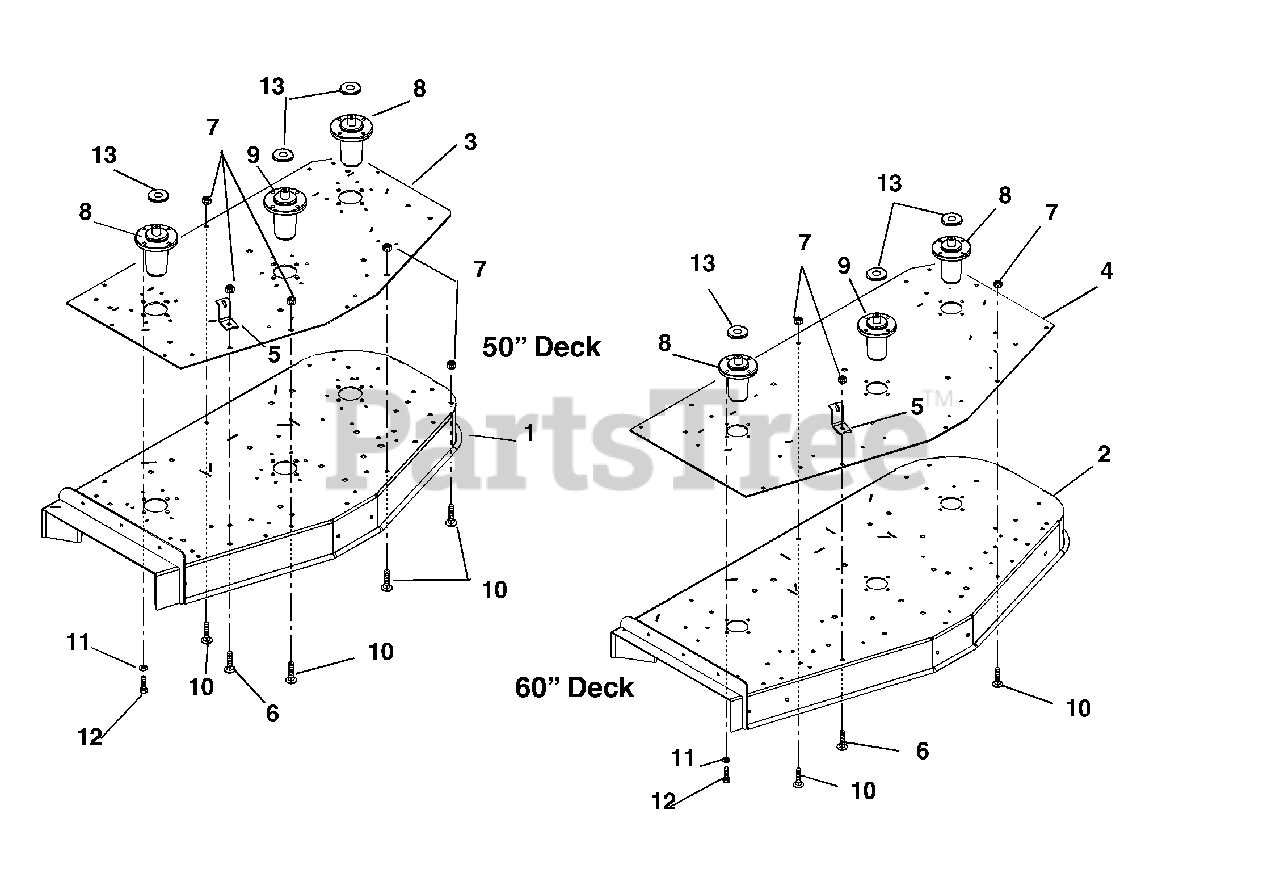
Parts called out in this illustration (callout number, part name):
1	Weldment, 50"Deck (Side Discharge)
2	Weldment, 60" Deck (Side Discharge)
3	Plate, 50" Reinforcement
4	Plate, 60" Reinforcing
5	Anchor, Spring
6	Bolt-Round Head Square Neck .38-16 x 1.25 Grade 2
7	Nut-Locking-Nylon .38-16
8	Assembly, Spindle L-Hub
9	Spindle Assembly (Center)
10	Bolt-Round Head Square Neck .38-16 x 1.00 Grade 2
11	Washer-Locking .38 x .094
12	Bolt-Hex .38-16 x 1.00 Grade 5
13	Slinger-Dust
